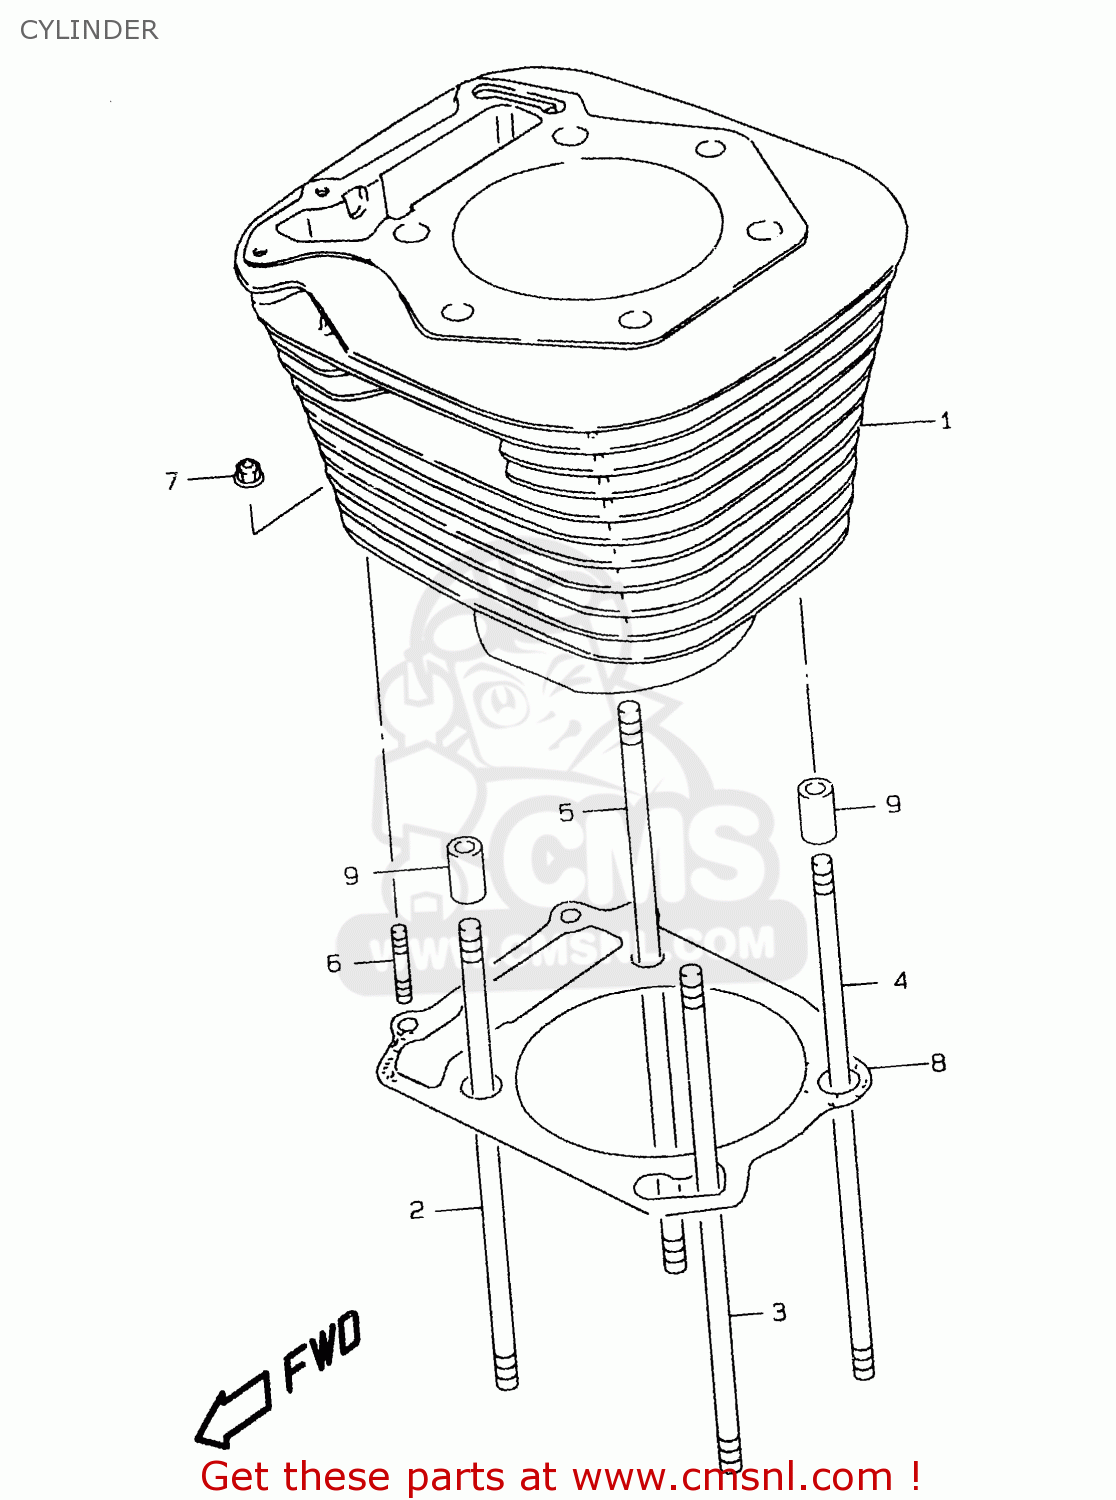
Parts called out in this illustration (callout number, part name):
1	CYLINDER
2	BOLT,STUD
3	BOLT,STUD
4	BOLT,STUD
5	BOLT,STUD
6	STUD 6X20
7	NUT
8	GASKET,CYLINDER (NAS)
9	PIN
